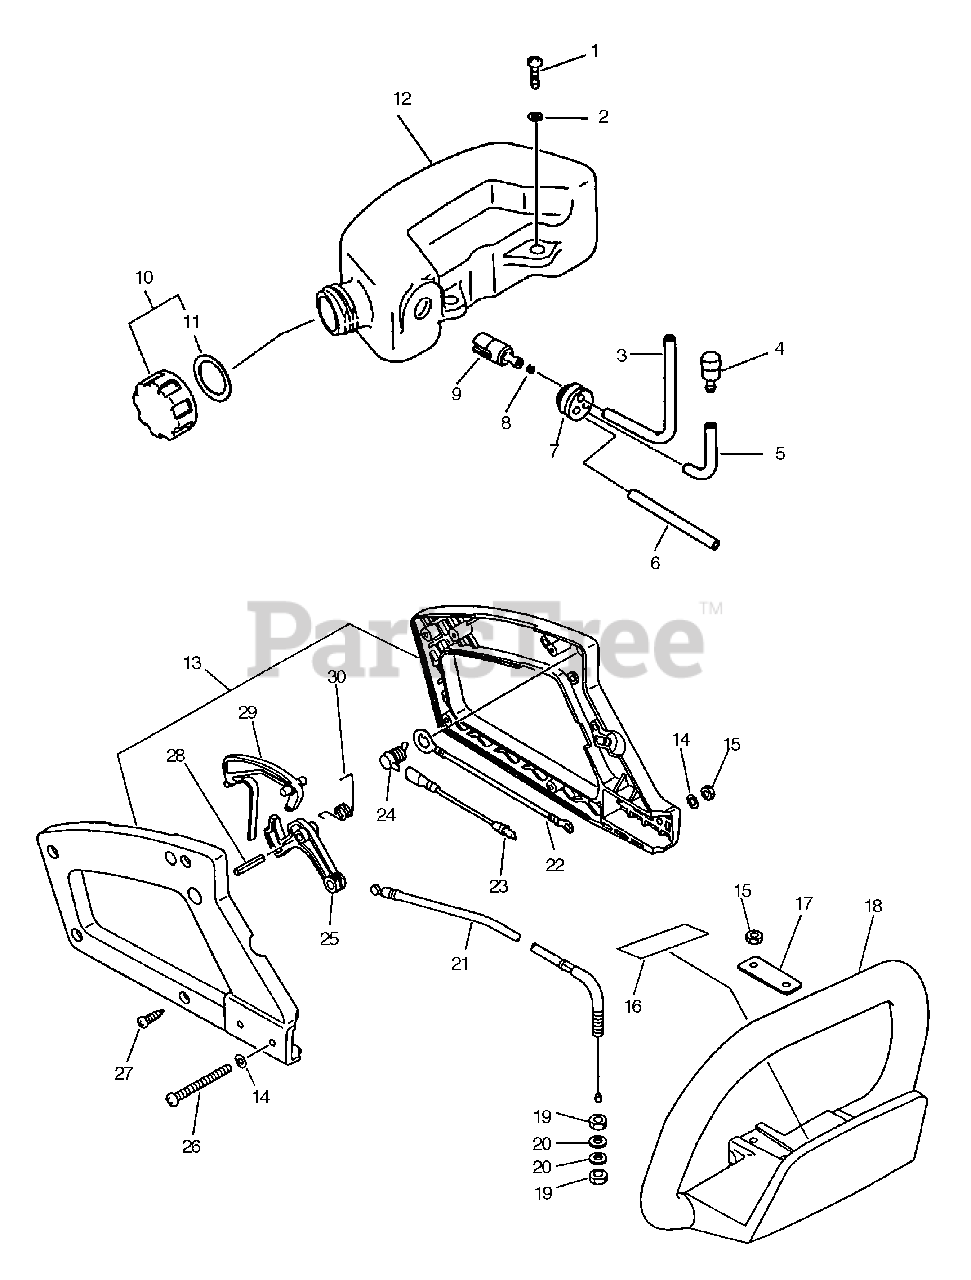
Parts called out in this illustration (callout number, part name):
1	SCREW - 5X16
2	WASHER - 5
3	PIPE - 3X5X195 -- BLACK
4	VENT, FUEL TANK
5	PIPE - 3X5X70 -- BLACK
6	PIPE - 3X6X110 -- CLEAR
7	GROMMET
8	CLIP - 6
9	FILTER, FUEL
10	CAP ASSY
11	GASKET, CAP
12	TANK, FUEL
13	HANDLE ASSY - REAR
14	WASHER - 5
15	LOCKNUT - 5
16	LABEL - CAUTION
18	HANDLE - FRONT
20	WASHER - 6
21	CABLE, THROTTLE
22	LEAD - GROUND
23	LEAD - GROUND
24	IGNITION SWITCH ASSY
25	TRIGGER, THROTTLE
26	SCREW - 5X40
27	SCREW - 4X16
28	PIN - SPRING -- 5X25
29	LOCKOUT, THROTTLE
30	SPRING, TRIGGER
